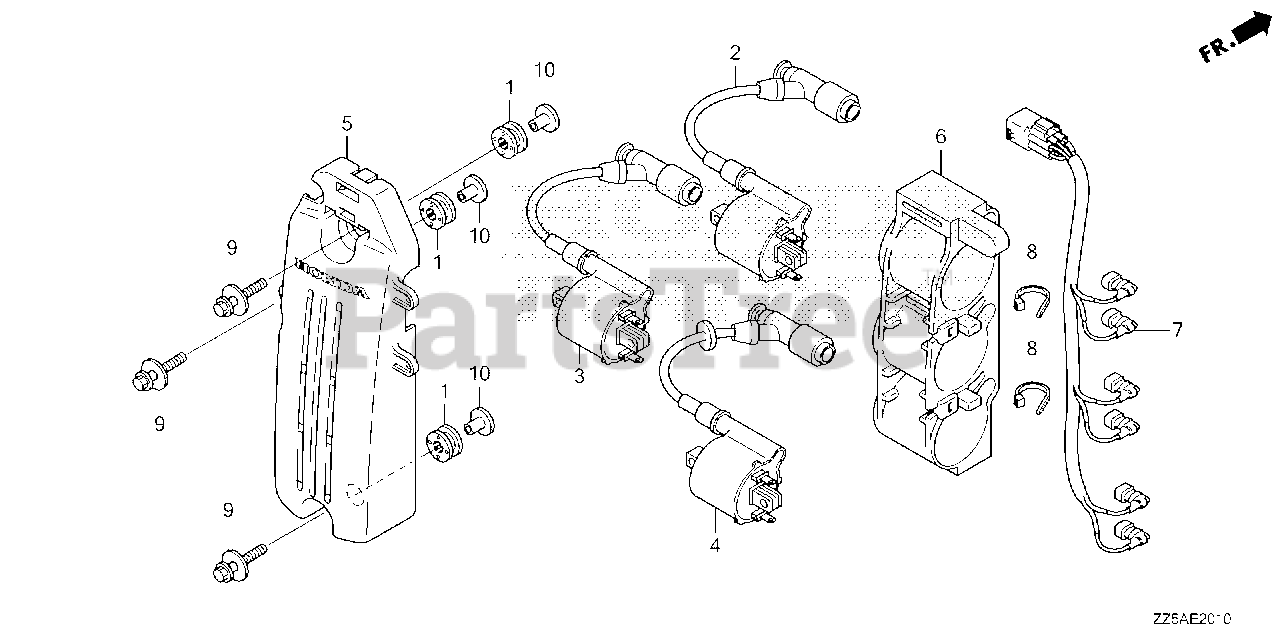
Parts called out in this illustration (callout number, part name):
1	GROMMET, ELECTRONIC PARTS CASE
2	COIL, IGNITION (1)
3	COIL, IGNITION (2)
4	COIL, IGNITION (3)
5	CASE, IGNITION COIL
6	SUSPENSION, IGNITION COIL
7	WIRE ASSY., IGNITION COIL
8	BAND, WIRE
9	BOLT-WASHER (6X25)
10	COLLAR, MOUNTING (6MM)
